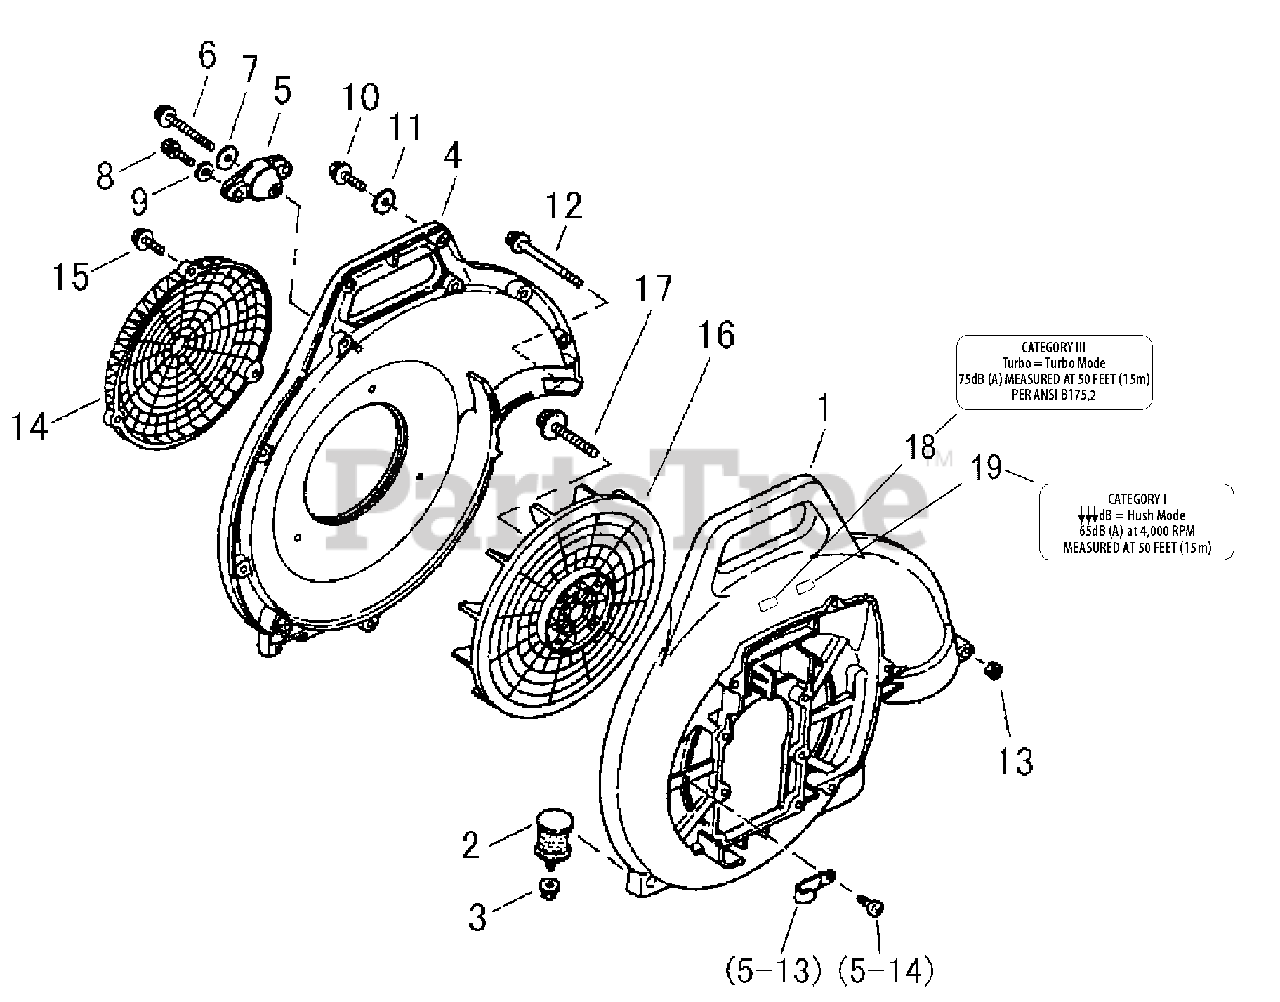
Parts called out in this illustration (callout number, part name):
1	COVER, FAN - OUTER
2	CUSHION
3	NUT - 6 -- FLANGE
4	COVER, FAN - LEFT
5	CUSHION
6	BOLT - 5 -- TAPPING
7	COLLAR - 25X5.5X2
8	SCREW - 5X16
9	COLLAR
10	BOLT - 5X20
11	WASHER - 5
12	SCREW - 5X70
14	COVER, INTAKE
15	BOLT - TAPPING
16	FAN
17	BOLT - 6X40
18	LABEL - NOISE 75dB(A) CAT III
19	LABEL - NOISE 65dB(A) CAT I
